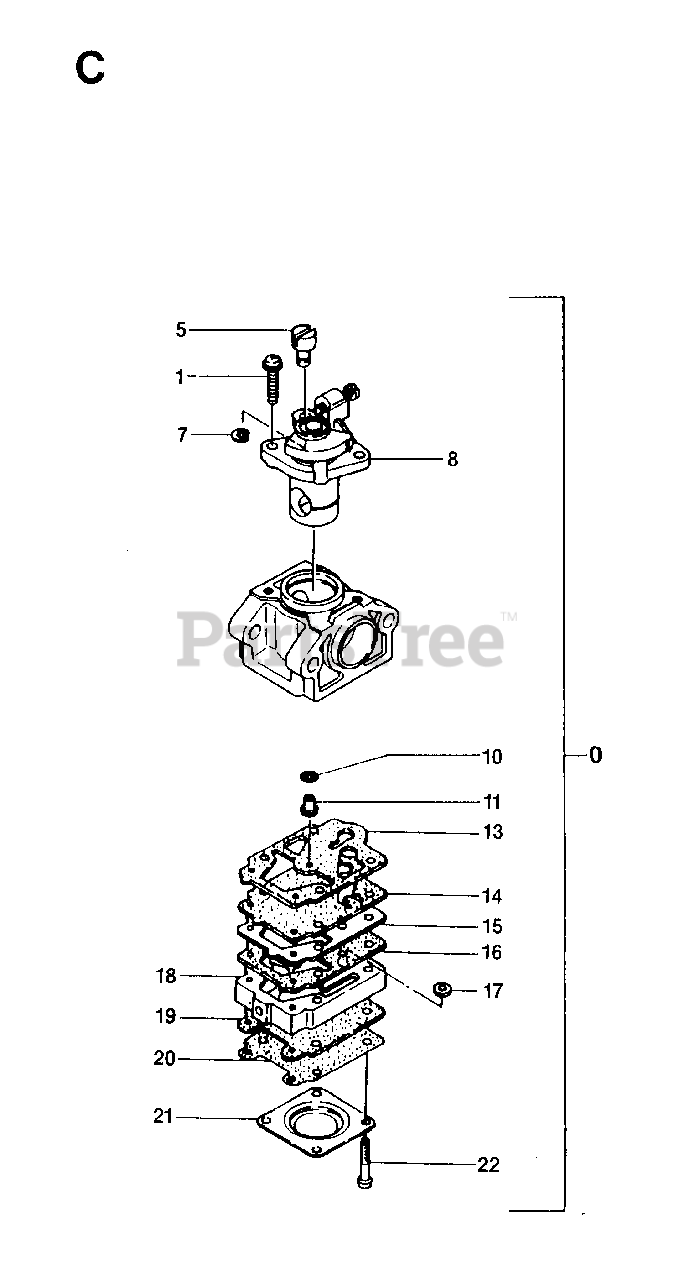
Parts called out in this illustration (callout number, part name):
7	RETAINING RING
8	THROTTLE VALVE CPL.
18	PUMP BODY COMP.
20	METERING DIAPHRAGM
21	DIAPHRAGM COVER
